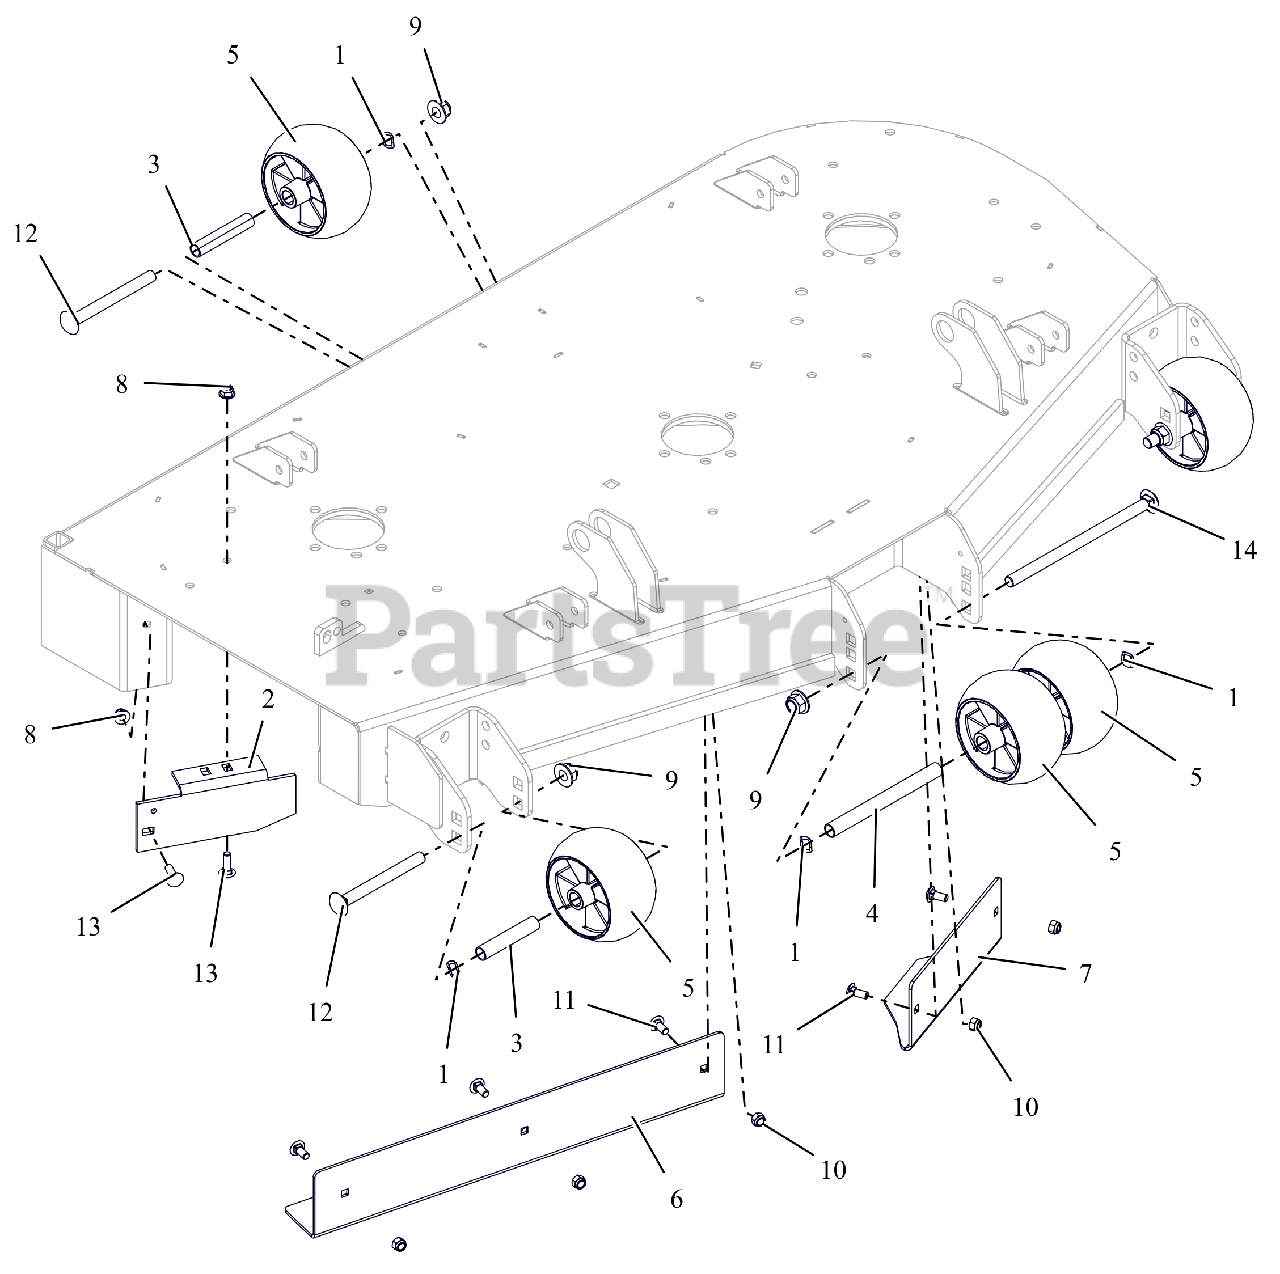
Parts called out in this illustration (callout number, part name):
1	WAVE WASHER .531X.781X.125FH
2	44"-48" SIDE DISCH BAFFLE -RED
3	SPACER, .510X.625X3.35
4	SPACER, .510X.625X6.50
5	ANTI-SCALP WHEEL - 5X3 CTR
6	BAFFLE, 48" RH VACUUM (RED)
7	BAFFLE, 44/48" LH VACUUM (RED)
8	NUT,NYL-FLG .31-18 GF ZCC
9	NUT,NYL-FLG .50-13 GF ZCC
10	NUT,NYL .31-18 G5 ZCC
11	BLT,RHSN .31-18X.75 G5 ZCC
12	BLT, RHSN .50-13X5.00 G5 ZCC
13	BLT,RHSN .31-18X1.00 G5 ZCC
14	BLT, RHSN .50-13X8.50 G5 ZCC
